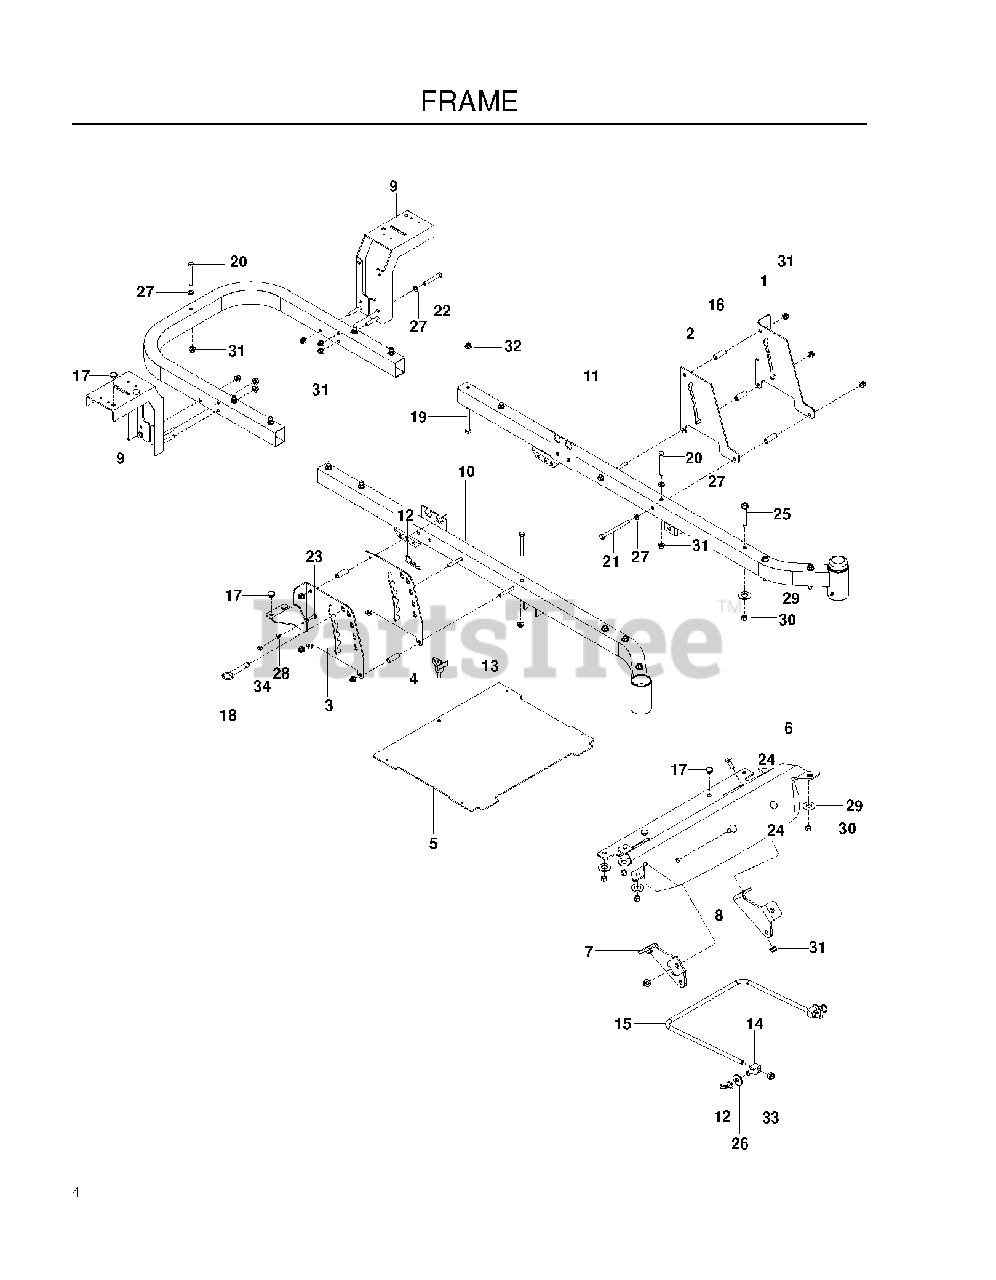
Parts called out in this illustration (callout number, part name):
1	PLATE, OUTER BRAKE, BLACK
2	PLATE, BRAKE LATCH, BLACK
3	PLATE, DECK HEIGHT, BLK EZ
4	PLATE, DECK HEIGHT, BLACK
5	PLATE, FOOT W/DECALS RZ
6	FOOT.REST.MED.ORANGE
7	MOUNT, STRUT, RT, BLK
8	MOUNT, STRUT, LT, BLK
9	SUPPORT, FENDER, BLACK
10	FRAME, RT, ORANGE
11	FRAME, LT, ORANGE
12	HAIRPIN #4
13	KNOB W/STUD
15	LINK, FRONT SUSP.
16	SPACER, .334 ID X .5 OD X 1.5
17	GROMMET, BUMPER
19	HCS 3/8C X 3
20	HCS 5/16C X 2-3/4
21	HCS 5/16C X 4
23	HCS 1/4C X 1
24	RHSNB 3/8C X 1
25	ENGINE BOLT, SPECIAL
26	WASH USS FLAT 1/2
27	FLAT WASHER 5/16 SAE
28	WASHER 1/4 SAE
29	RP WASHER 3/8 FLAT
30	NUT HEX 3/8-16 NYLON, THIN
31	5/16-18 NYLOC FLANGE NUT
32	NUT 3/8-16 HEX FLG NYLOC ZD
33	7/16-14 HEX NUT W/NYL RING ZD
34	RP_NUT 1/4-20 NYLOC
